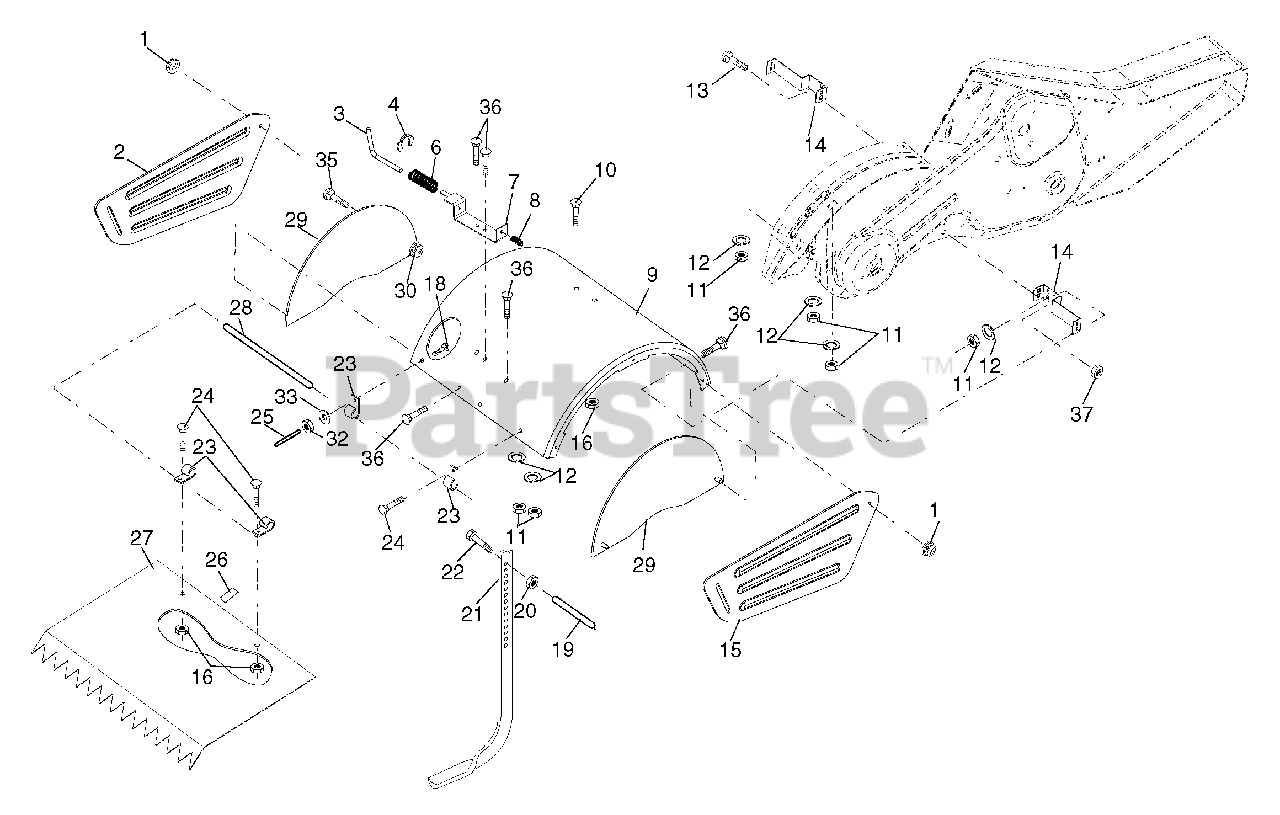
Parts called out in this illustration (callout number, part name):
1	Nut, Lock Hex Flange 5/16-18
2	Shield, Side, Outer L. H.
3	Pin, Stake, Depth
4	Ring, Klip
6	Spring
7	Bracket, Latch
8	Spring, Depth Stake
9	Shield, Tine
10	Bolt 5/16-18 x 3/4 ZNC
11	Nut, Hex 5/16-18
12	Washer, Lock 5/16
13	Bolt, Carriage 5/16-18 x 1-1/4
14	Bracket, Shield Tine
15	Shield, Side, Outer R.H.
16	Nut, Hex Flange 1/4-20 unc
18	Bolt, Carriage 1/4-20 x 1-1/4 Gr. 5
19	Grip
20	Nut, Hex 3/8-16
21	Stake, Depth
22	Bolt, Hex 3/8-16 x 2
23	Hinge
24	Bolt, Carriage 1/4-20 x 1/2 Gr. 5
25	Cap, Vinyl
26	Pad, Idler
27	Shield, Leveling
28	Pin, Hinge
29	Shield, Side
30	Locknut, Flange 5/16-18
32	Nut Fin Hex 1/4-20 unc
33	Washer Lock Hvy Helical 1/4
35	Bolt Carr. 5/16-18 x 5/8
37	Nut Lock 5/16-18
